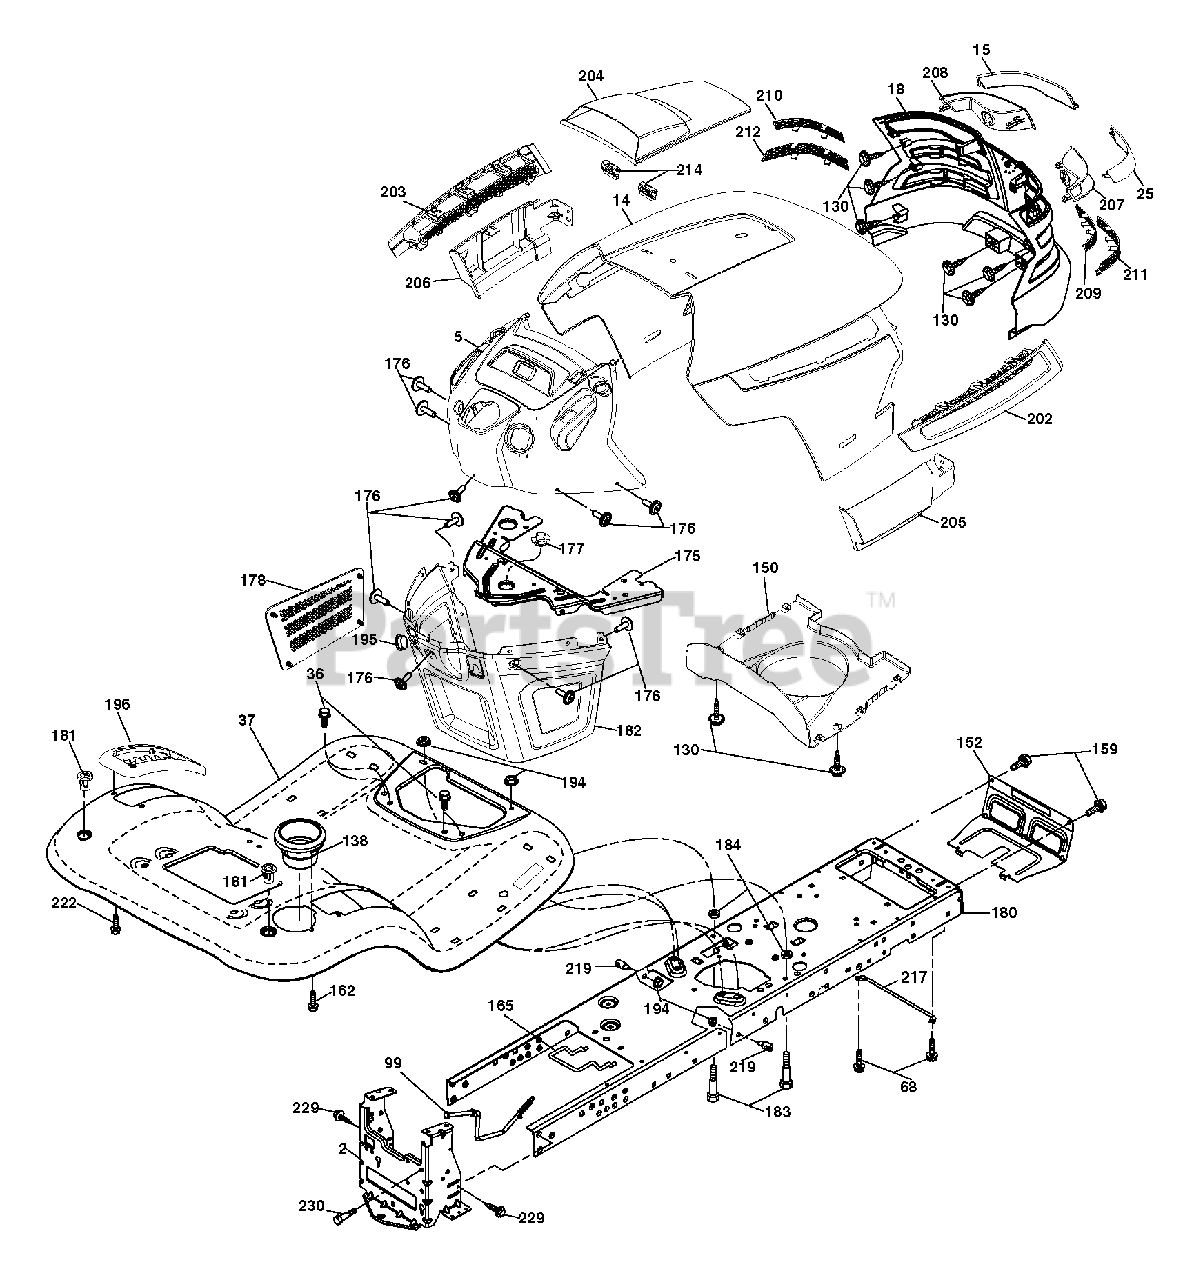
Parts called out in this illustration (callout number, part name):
5	Dash
14	Hood
18	Grille/Lens Asm.
36	Screw 5/16-18 x 3/4
37	Fender
68	Screw Thdrol 5/16-18 x 1/2
99	Rod Asm Bypass
130	Screw 10 x 3/4 Single Lead-Hex
138	Cupholder
152	Shield Browning
159	Screw 3/8-16 x 3/4
165	Support Tank Rear
175	Crossmember
176	Screw 10-24 x 5/8
177	Bushing Steering
178	Cargo Net Asm.
180	Chassis
181	Bushing Mtg. Fender Crgo
182	Dash Lower
183	Bolt Fin Hex 5/16-18 unc x 1-1/4
184	Spacer Fender
194	Nut Lock Hex Flange 5/16-18
195	Plug Hole Dash Lower
196	Console Asm. Deck Lift
202	Vent Side Hood RH
203	Vent Side Hood LH
204	Vent Top Hood
205	Skirt Hood Side RH
206	Skirt Hood Side LH
209	Insert Hex Top RH
210	Insert Hex Top Lh
211	Insert Hex Bottom RH
212	Insert Hex Bottom LH
214	Clip Retainer Tinner
217	Rod Pivot
219	Stud Fastner
222	Screw Thdrol 1/4-20 x 5/8
229	Screw Hexwsh Thdr 3/8-16 x 3/4
230	Bolt Shoulder 5/16-18
